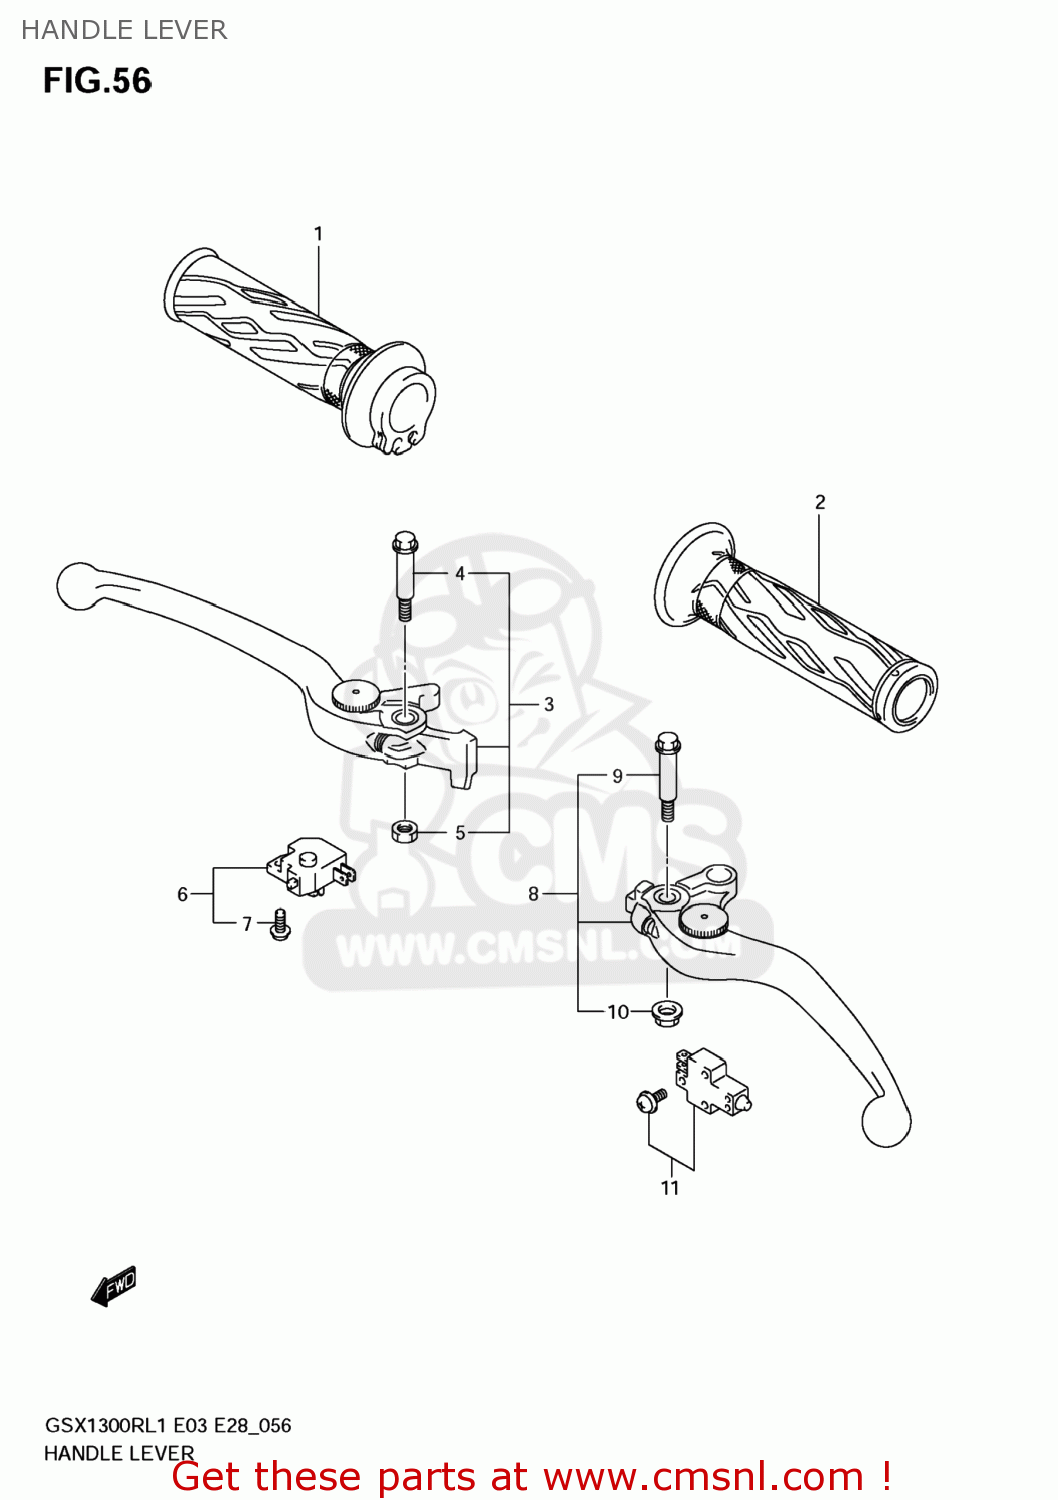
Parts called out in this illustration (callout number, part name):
1	GRIP,THROTTLE
2	GRIP,L
3	LEVER ASSY,FR
4	BOLT,LEVER PIV
5	NUT
6	SWITCH ASSY,ST
7	SCREW
8	LEVER ASSY,CLU
9	BOLT,LEVER PIV
10	NUT
11	SWITCH ASSY,CLUTCH
